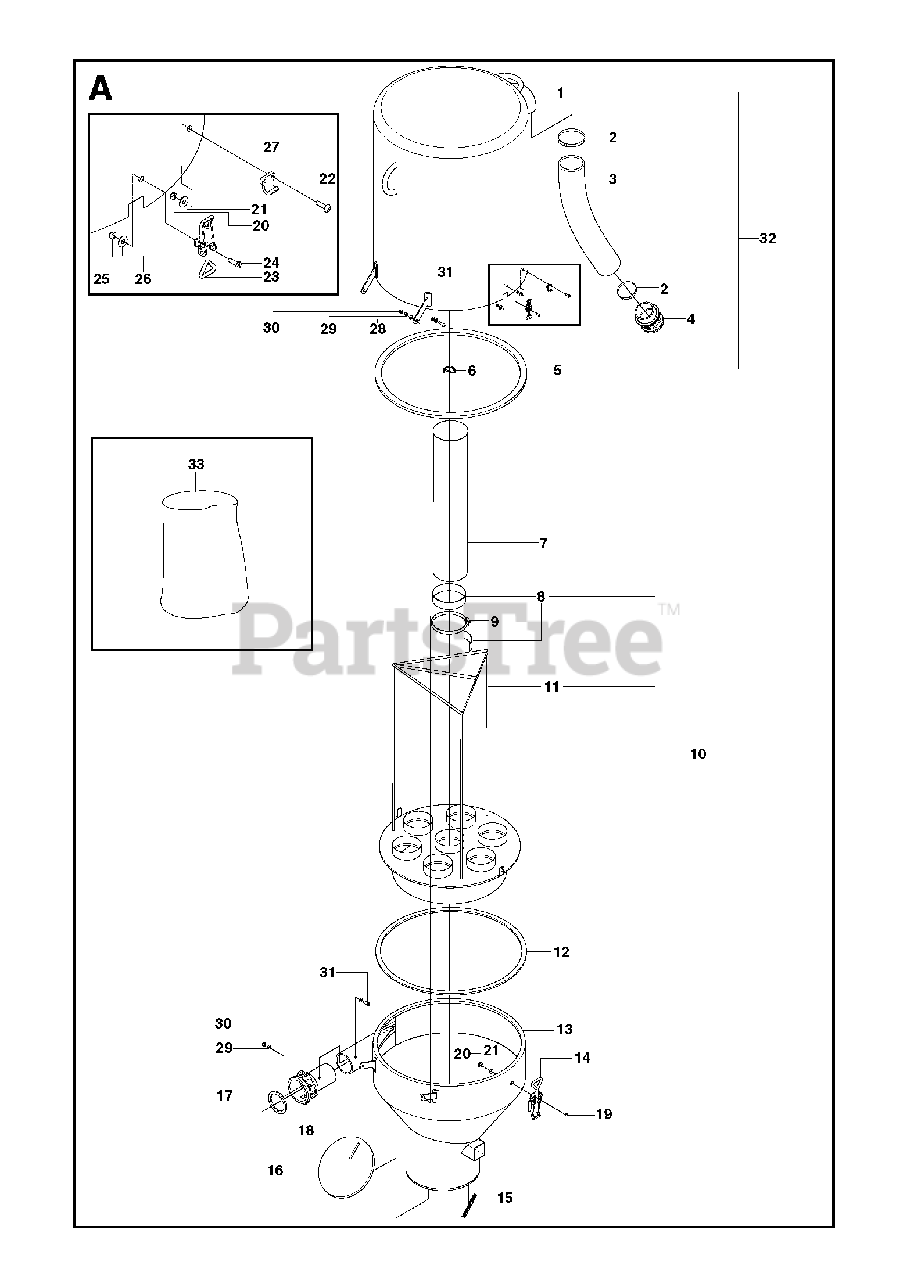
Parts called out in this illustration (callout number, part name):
8	FILTERIncludes 7 items
20	HEXAGON LOCKING NUT
25	HEXAGON LOCKING NUT
26	WASHER
29	WASHER
30	HEXAGON LOCKING NUT
33	BAGSIncludes 200 items
